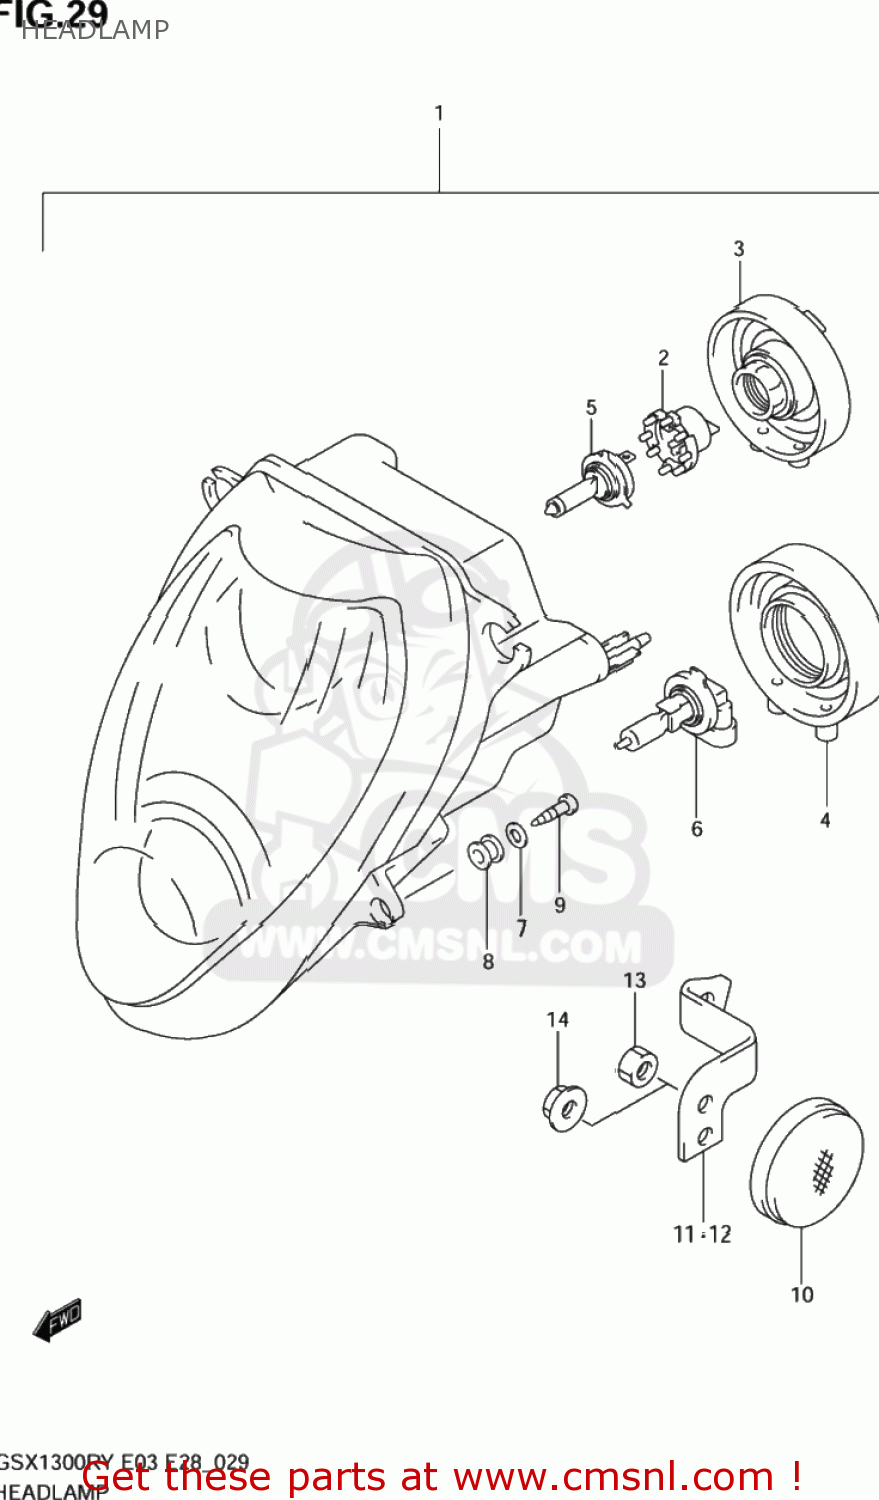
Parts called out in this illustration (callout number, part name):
1	HEADLAMP ASSY
2	ADAPTER ASSY
3	SOCKET,COVER
4	SOCKET,COVER
5	BULB(12V55W/H7/PX26D/PHILIPS)
6	BULB(12V60W,HB3,#9005)
7	WASHER(5.5X18X1)
8	CUSHION
9	SCREW
10	REFLECTOR,REFLEX
11	BRACKET,FR SIDE RR,R
12	BRACKET,FR SIDE RR,L
13	NUT
14	NUT
